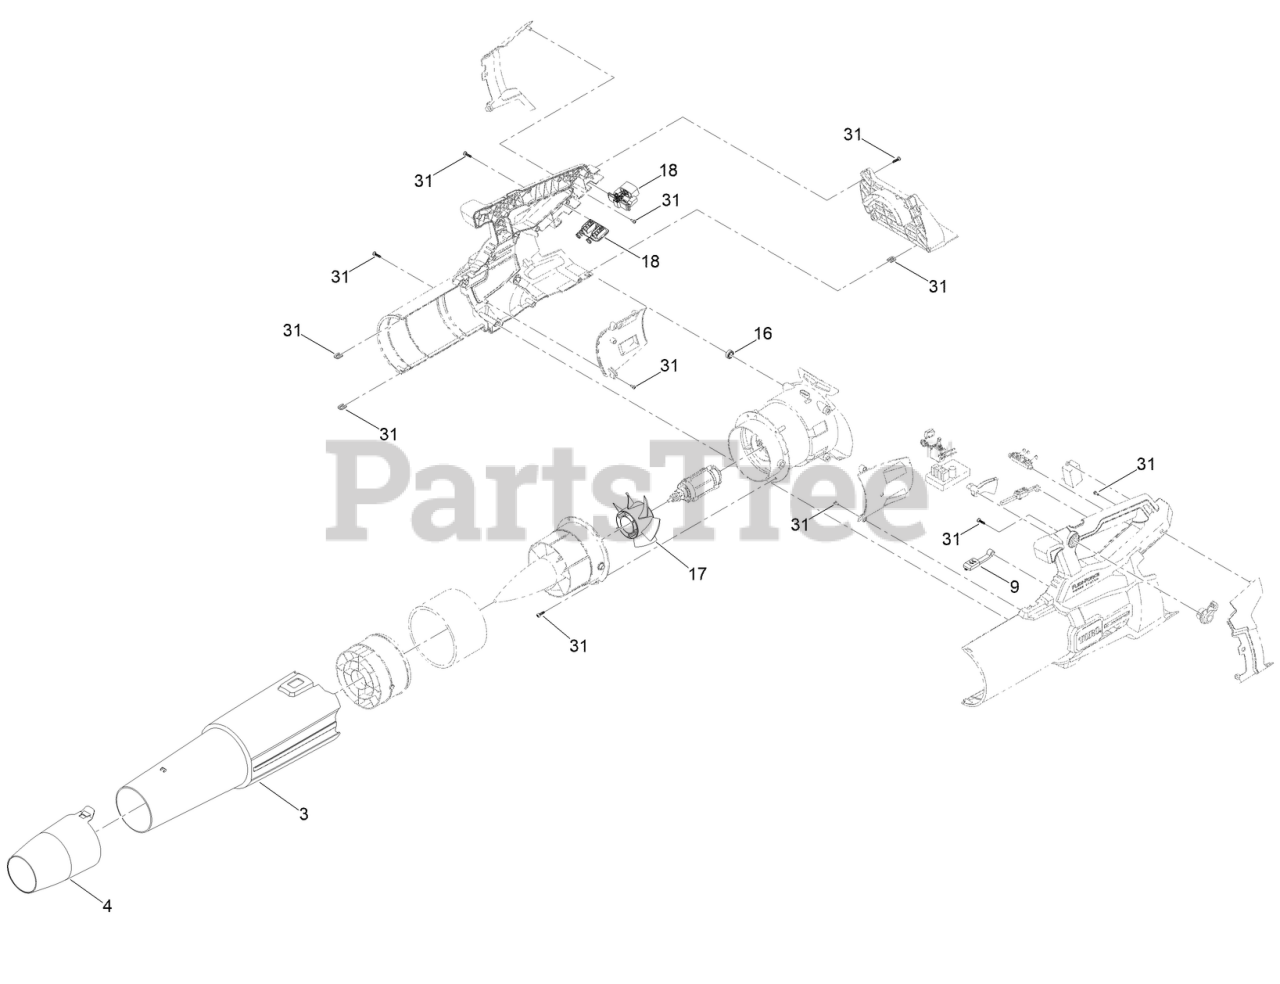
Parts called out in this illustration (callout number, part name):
3	60V AXIAL BLOWER BLOW TUBE
4	60V AXIAL BLOWER REDUCER NOZZLE
9	BLOWTUBE RELEASE SERVICE KIT
16	60V AXIAL BLOWER ISOLATOR KIT
17	60V BLOWER FAN SERVICE ASM
18	60V AXIAL BLOWER BATTERY LATCH
31	60V AXIAL BLOWER HARDWARE KIT
